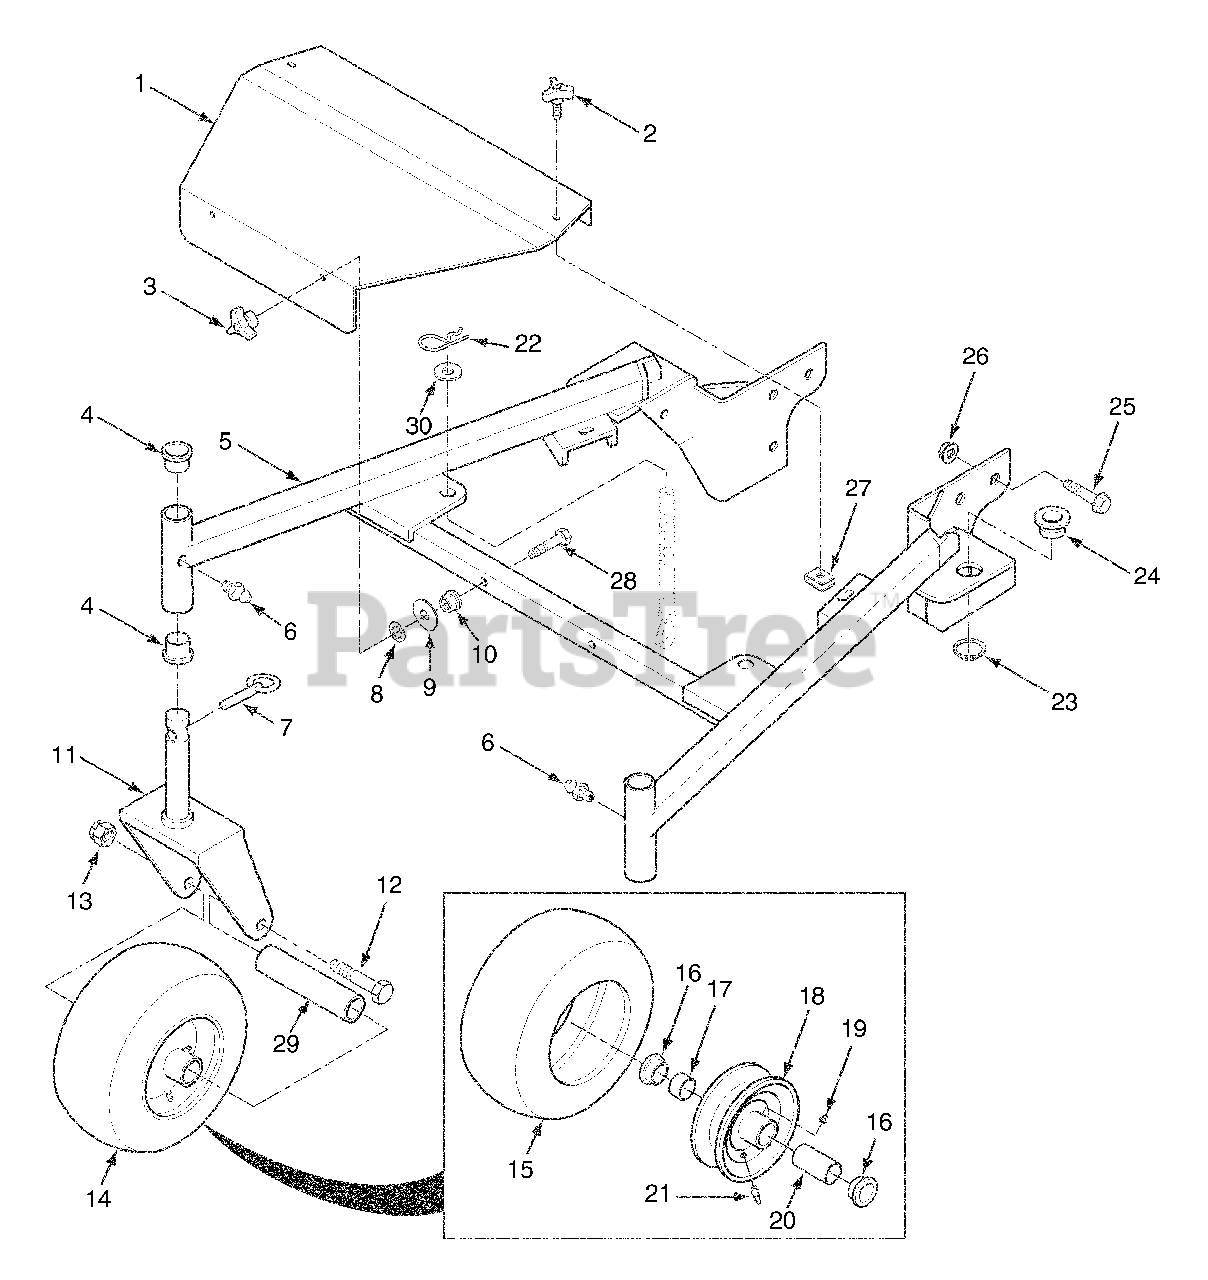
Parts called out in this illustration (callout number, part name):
1	Belt Cover With Decals
2	Knob With Stud
3	Knob, Deck Cover Mounting
4	Bushing, Caster
5	Frame Weldment, Deck Mounting
6	Grease Fitting Str. 1/4-28 Self Tap
7	Quick Pin, .438" Dia.
8	Nut, Push-On - 3/8" Dia.
9	Flatwasher, 3/8" (.391 x .938 x .105)
10	Nut, 3/8-16 Serrated Flange Hex Head
11	Yoke, Caster Wheel
12	Capscrew, Hex Head 1/2-13 x 6-1/2"
13	Locknut, 1/2-13 Elastic Stop
14	Wheel Assembly, Caster
15	Tire, 11 x 4.00-5
16	Retainer
17	Roller Bearing
18	Rim, 5.0" x 2-3/4"
19	Grease Fitting Str. 1/4-28
20	Roller Bearing .625 x 3.25"
21	Tire Valve
22	Hair Pin Cotter, .177 x 3-1/4"
23	Retaining Ring 1.50 Ext.
24	Bushing, Deck Adjustment Pin
25	Capscrew, 1/2-13 x 1" Serrated Flange Hex Head
26	Nut, 1/2-13 Spiralock
27	U-Nut, 3/8-16
28	Capscrew, Hex Head 3/8-16 x 2-1/4"
29	Sleeve, Caster Wheel
30	Flatwasher, 5/8" - (.688 x 1.75 x .134)
